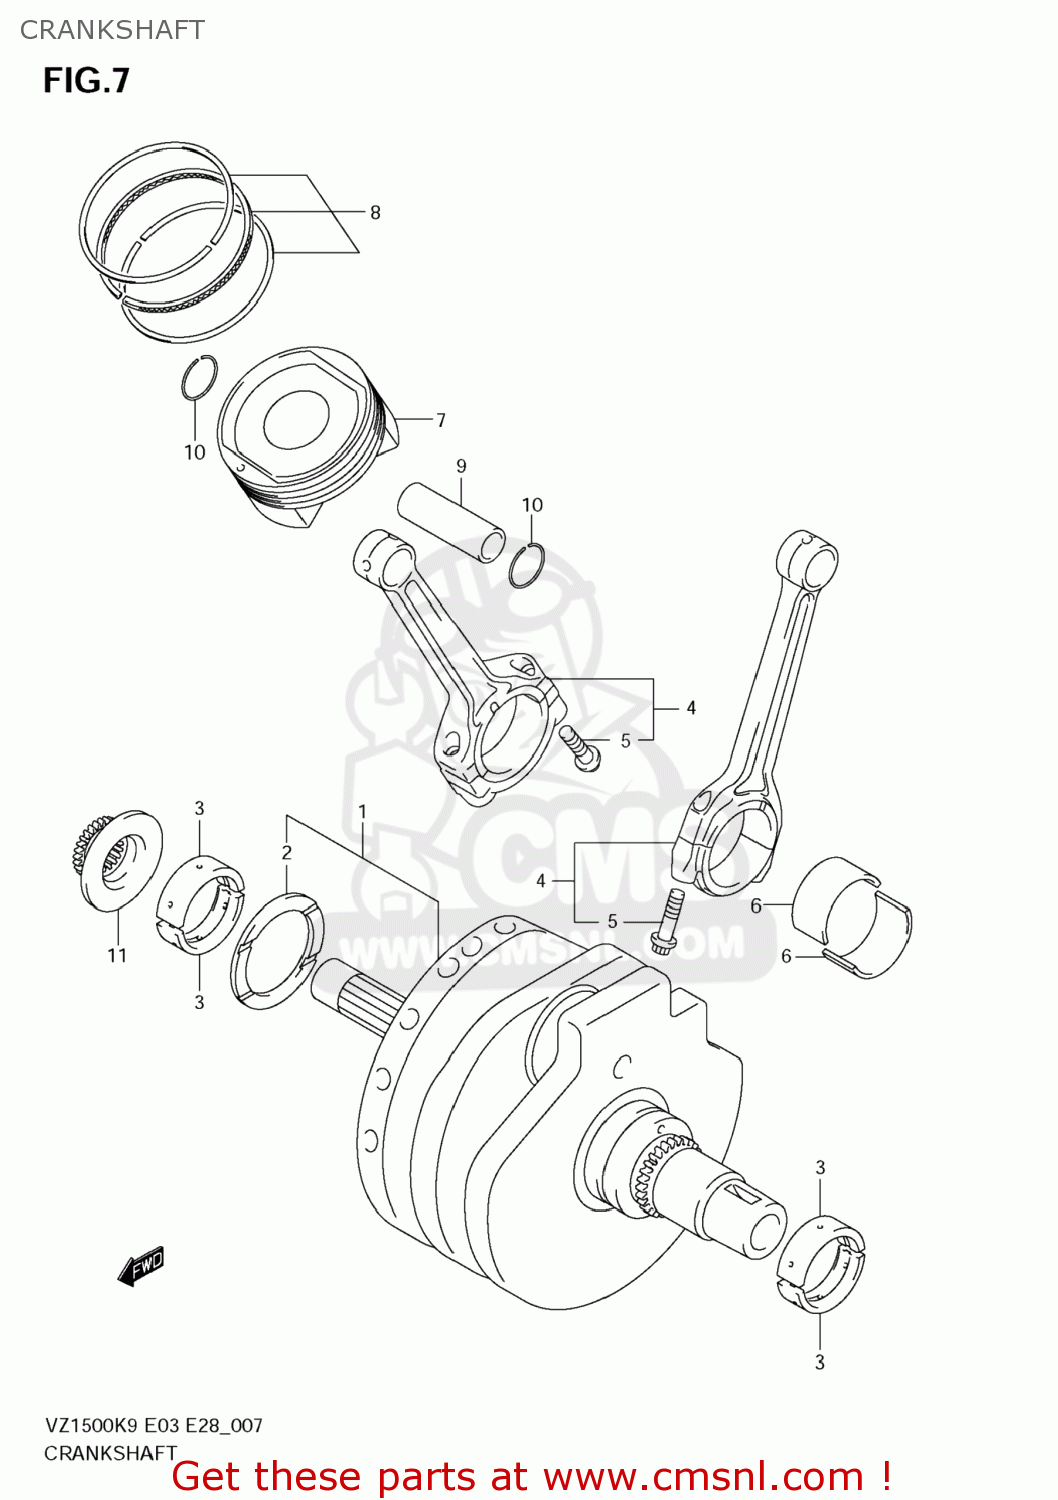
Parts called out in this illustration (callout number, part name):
1	CRANKSHAFT SET
2	BEARING,CRANK THRUST
3	BEARING,CRANKSHAFT
4	CONNECTING ROD ASSY
5	BOLT,CONNECTING ROD
6	BEARING,CRANK PIN
7	PISTON
8	RING SET,PISTON
9	PIN,PISTON
10	CIRCLIP
11	SPROCKET,CAM CHAIN DRIVE,R
